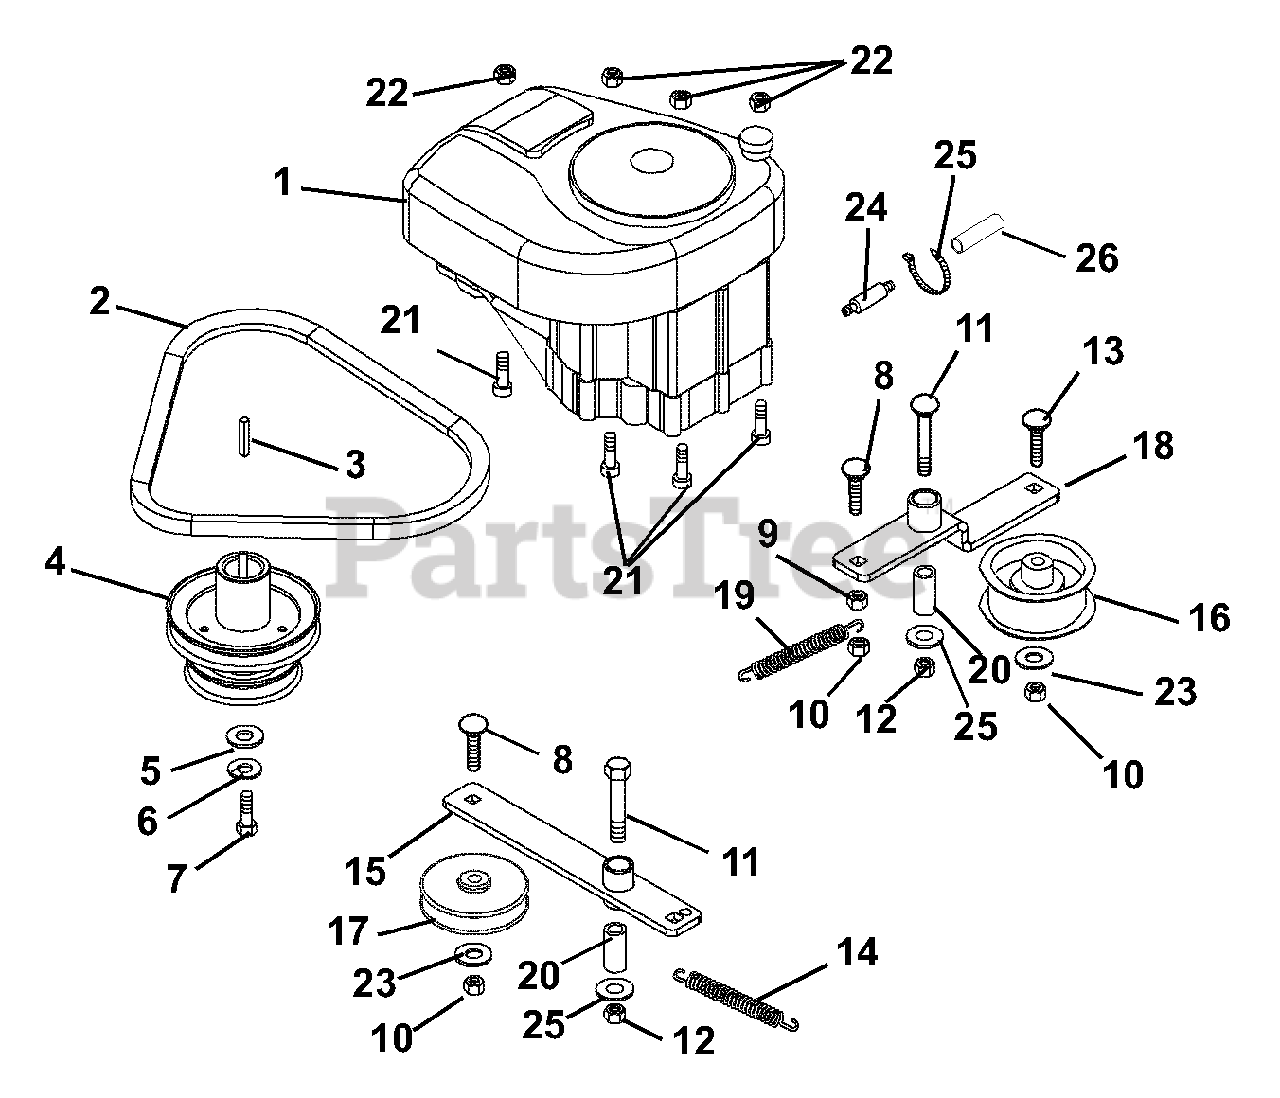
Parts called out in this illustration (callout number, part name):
1	ENGINE, B&S MODEL 21, 10.5 HP
1	ENGINE, B&S MODEL 28, 14.5 HP
2	V-BELT, 4L-RAW EDGE
3	KEY-STR .25X1.75X.25
4	STACK, RER ENGINE SHEAVE
5	WSHR-FL-STL .469X2.00X.25 YWZC
6	@WSHR-LK .44X.109 REG YWZC
7	BLT-HEX .44-20X1.75 GR5 YWZC
8	@BLT-RDHDSQNK .38-16X1.25 G5YZ
9	@NUT-SPNLK-FLG .375-16 YWZC
10	NUT-LK-TOP-FLG .38-16 BLKZC
11	@BLT-HEX .50-13X2.25 GR5 YWZC
12	NUT-LK ESNA THIN .50-13 YWZC
13	@BLT-RDHDSQNK .38-16X2.00 G5YZ
14	SG-TENS .095X.500X5.5 WLD60 YZ
15	IDLER, DRIVE (WLDMNT)
16	IDLER 2.75X1.25
17	IDLER-V 3X.38
18	IDLER, RER PTO (WLDMNT)
19	SG-TENS .093X.75X4.0 WLD40
20	BSHG-SLV .500X.750X1.560
21	SCR-SKH BTHD .31-18 X 1.50 GR8
22	NUT-LK-TOP-FLG .31-18 BLKZC
23	@WSHR-FL-STL.38X.875X.083 YWZC
24	VALVE, OIL DRAIN
25	CABLE TIE LG 5-1/2
26	TUBE, OIL DRAIN 8" CLEAR VINYL
27	@WSHR-FL-STL.563X1.38X.109YWZC
